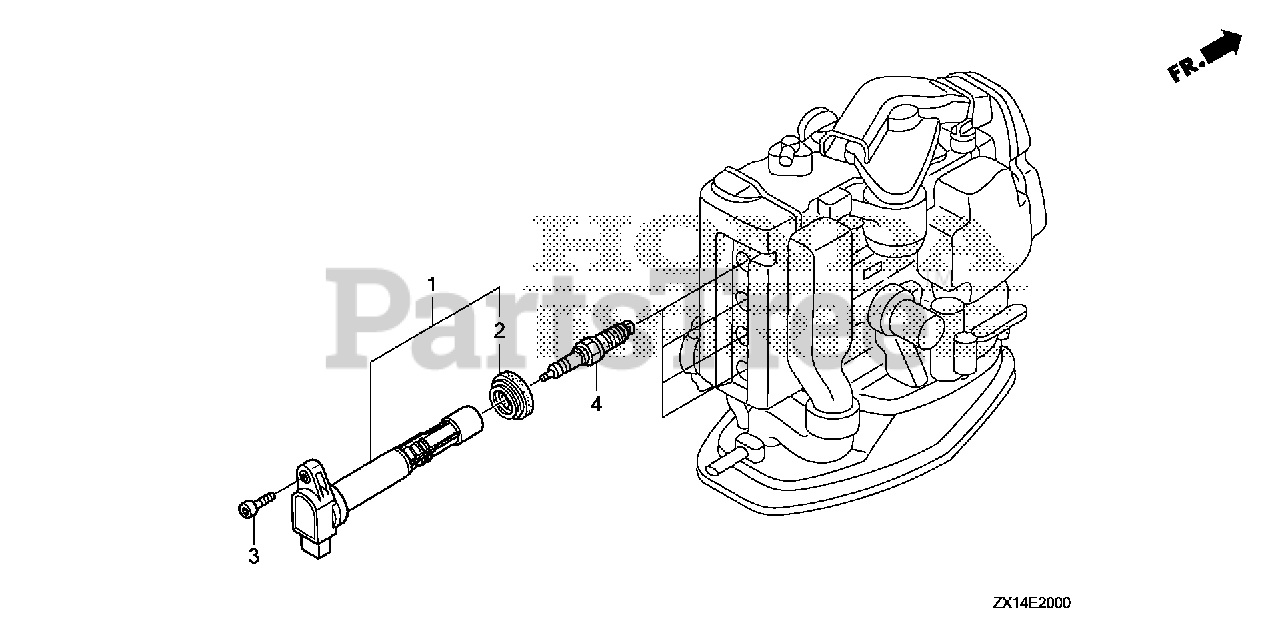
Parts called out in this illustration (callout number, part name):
1	COIL, PLUG HOLE
2	SEAL, PLUG HOLE
3	BOLT, SOCKET (6X25)
4	SPARK PLUG (KJ20DR-M11) (DENSO)
4	SPARK PLUG (SKJ20DR-M11) (DENSO)
4	SPARK PLUG (ZFR6K-11) (NGK)
4	SPARK PLUG (IZFR6K-11) (NGK)
